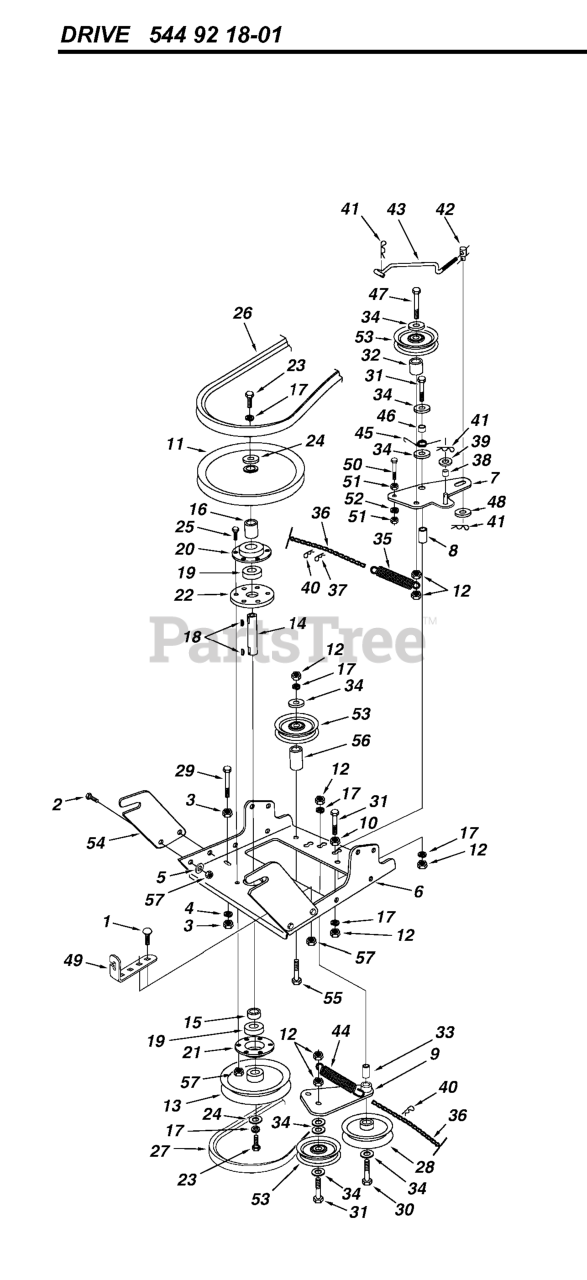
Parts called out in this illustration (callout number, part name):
1	RP BOLT 5/16-18 X3/4 ZN/YEL GR
2	BOLT.FIN.HEX.5/16-18X3/4
5	WASHER BRB 8.4X17
6	FRAME 25727
7	IDLER ARM 63904
8	SPACER 24286
9	IDLER BRACKET 63762
11	PULLEY 46981
14	SHAFT 738-0680
15	SPACER 750-0456
16	SPACER 750-0660
17	WASHER BRB 8.4X17
18	KEY 741-0161
19	BALL BEARING 741-0919
21	HOUSING 15296A
22	SPACER 14088B
26	BELT 46989
26	BELT 48138
27	BELT 47846
28	PULLEY 47044
29	BOLT 47025
32	SPACER 24571
33	SPACER 24472
34	WASHER
35	SPRING 46959
36	CHAIN 46963
38	SPACER 23727
39	WASHER - M6
42	TRUNNION 711-0198
44	SPRING 47620
45	SPRING 47607
47	BOLT 43509
48	WASHER 47605
49	BRACKET 24558
50	BOLT 49870
52	SPRING WASHER
53	PULLEY 48883
54	BRACKET 25728
55	BOLT 46938
56	SPACER 25780
